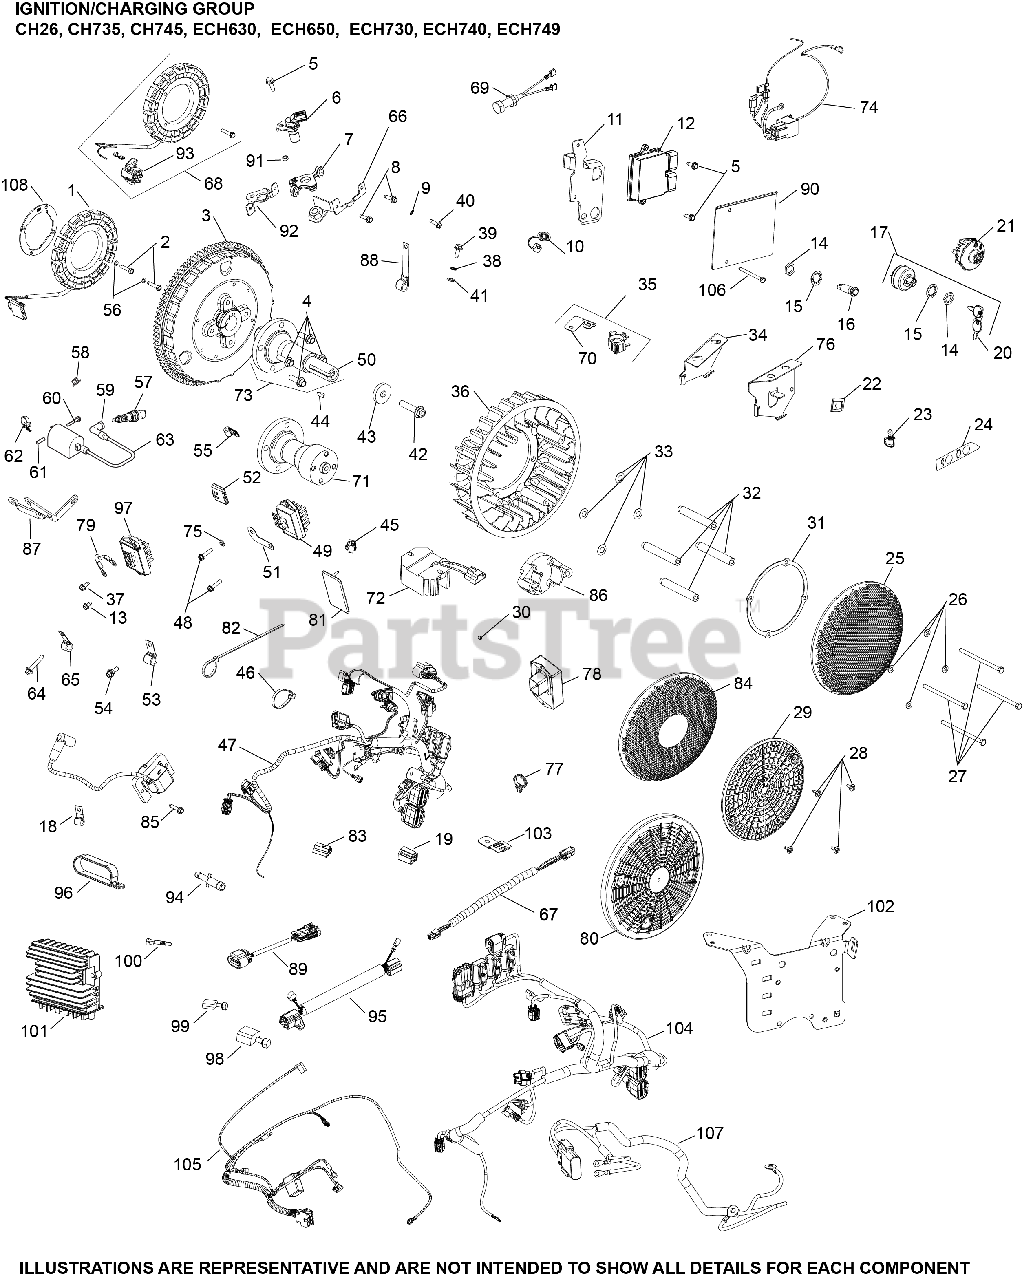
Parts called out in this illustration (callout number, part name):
2	SCREW, THREAD FORMING
3	FLYWHEEL, ASSEMBLY
4	SCREW, FLG M8X1.25X25
6	SENSOR, SPEED
8	SCREW, THREAD FORMING
9	WASHER, INT TOOTH LOCK #10
10	CAP, CONNECTOR
12	MODULE, ECU
26	WASHER, FLAT 1/4" (O.D. 5/8")
28	SCREW, CAP M6X1.0X99.5
30	SCREW, FLG M10X1.5X45 - (#25086361S)
31	RING, SUPPORT
33	WASHER, SPRING 10 MM
35	KIT, MOUNTING CLIP
36	FAN USE 24 755 253-S
38	WASHER, INT TOOTH LOCK 1/4"
41	WASHER, FLAT 1/4" (O.D. 1/2")
42	SCREW, SKT SET #10-24X1/4"
43	WASHER, FLAT 13/32"
44	KEY, 3/16" X 5/8"
46	TIE, WIRE
47	HARNESS, WIRING ASSEMBLY
57	PLUG, SPARK (STD)
63	COIL, IGNITION - EFI
64	SCREW, FLG M6X1.0X34
67	HARNESS, EFI DIAGNOSTIC EXTENSION
68	KIT, 25 AMP STATOR ASSY.
70	CLIP, MOUNTING BRACKET USE 25 154 21-S
71	SHAFT, FRONT
72	REG/RECT-25 AMP W/VOLT PROT.
81	KIT, COVER
83	CONNECTOR
84	SCREEN, GRASS
92	BRACKET, SENSOR
